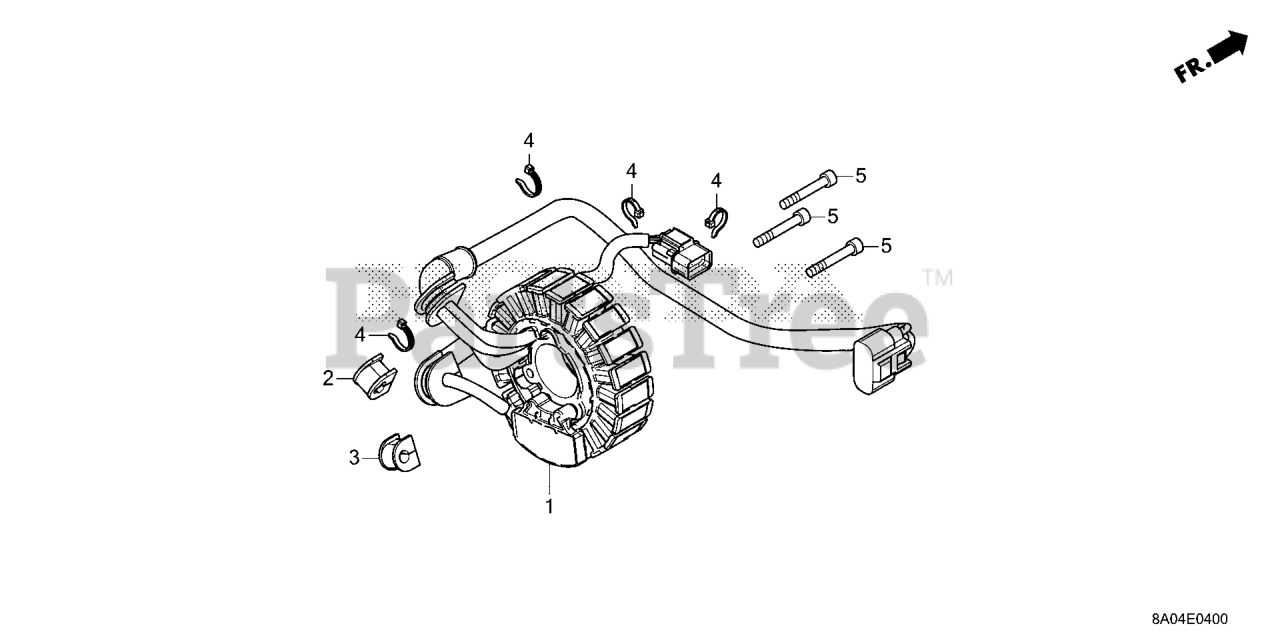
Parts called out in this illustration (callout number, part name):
1	STATOR ASSY.
2	GROM, MOTOR HARNESS
3	GROM, SENSOR HARNESS
4	BAND (BLACK 3.5X140)
5	BOLT, SOCKET (6X40)
